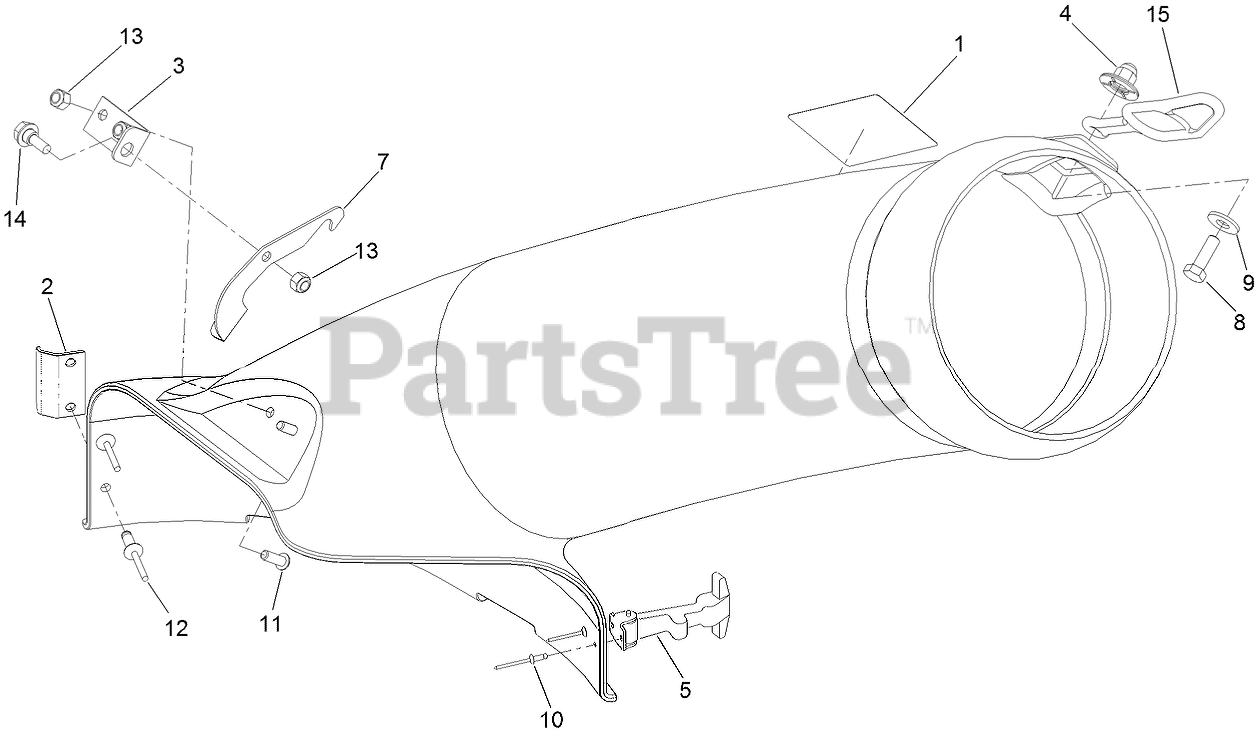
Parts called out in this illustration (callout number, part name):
1	DECAL-DANGER
2	BRACKET-ELBOW
3	PLATE-PIVOT
4	NUT-IMPELLER
5	HANDLE ASM
8	SCREW-HH
9	WASHER-FLAT
10	RIVET-POP
11	SCREW-HSBH
12	RIVET-BLIND
13	NUT-LOCK, NI
14	SCREW-SHOULDER, HHF
15	RETAINER-DUCT
